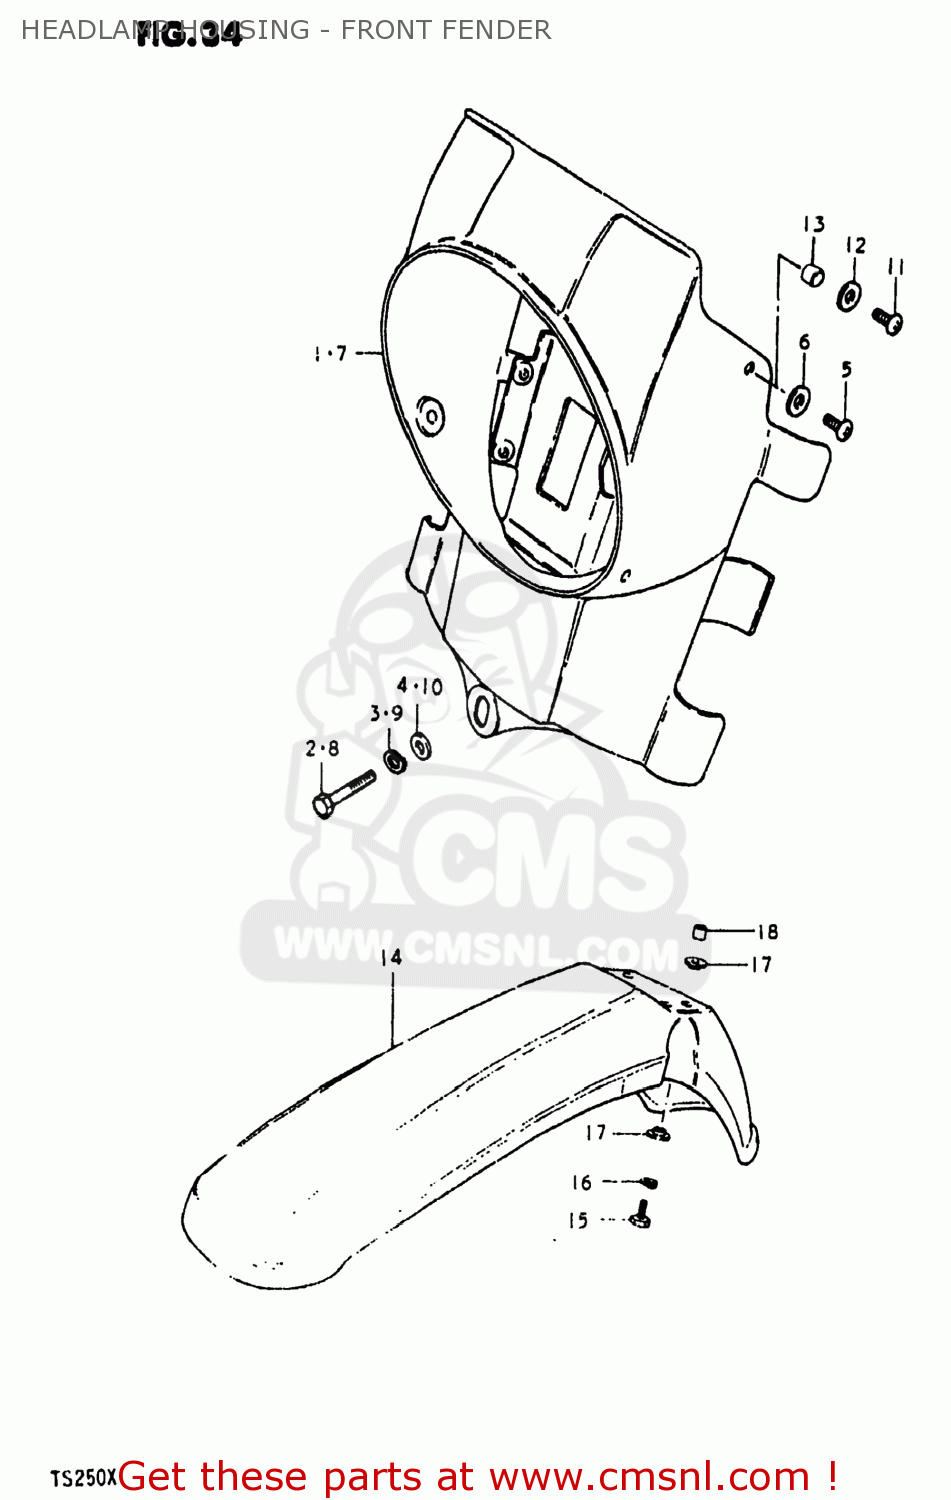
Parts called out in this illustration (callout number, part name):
1	HOUSING,HEADLAMP
2	BOLT
3	LOCK WASHER
4	WASHER
5	SCREW
6	WASHER (5.5X16X1.2)
7	HOUSING,HEADLAMP
8	BOLT
9	LOCK WASHER
10	WASHER
11	SCREW
12	WASHER (5.5X18X1.6)
13	SPACER (5.5X8X4)
14	FENDER,FRONT
15	BOLT
16	LOCK WASHER
17	SPACER
18	SPACER
